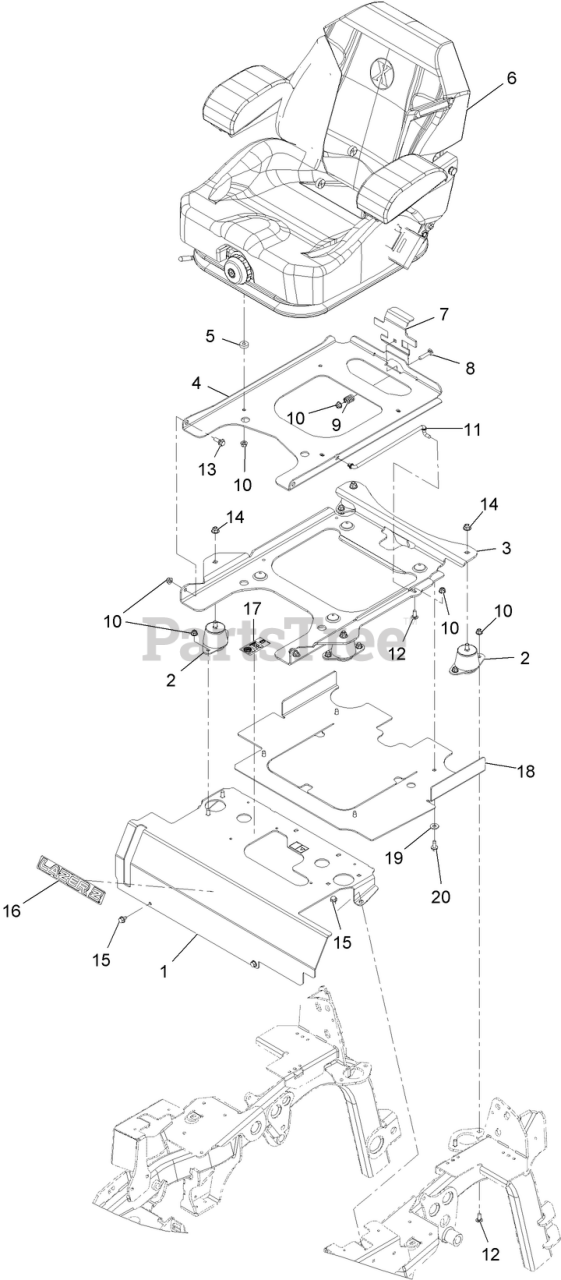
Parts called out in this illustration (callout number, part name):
1	MOUNT-SEAT W/DECALS
2	ISOLATOR-SEAT
3	Plate,Tilt Seat Support
4	PLATE-FRAME, SEAT
6	ASM-SUSPENSION SEAT, EXMARK
7	PLATE, SEAT LATCH
8	BOLT-CARR
9	SPRING-COMPRESSION
10	NUT-HF, NI
11	ROD-PROP
12	SCREW-CARR
13	SCREW-SHOULDER
14	NUT-HF, NI
16	DECAL, LAZER MODEL
17	DECAL-TRANS FLUID
18	SHIELD-HEAT
19	WASHER-FLAT
20	Screw-HWH 5/16-18 X 3/4 Tf
